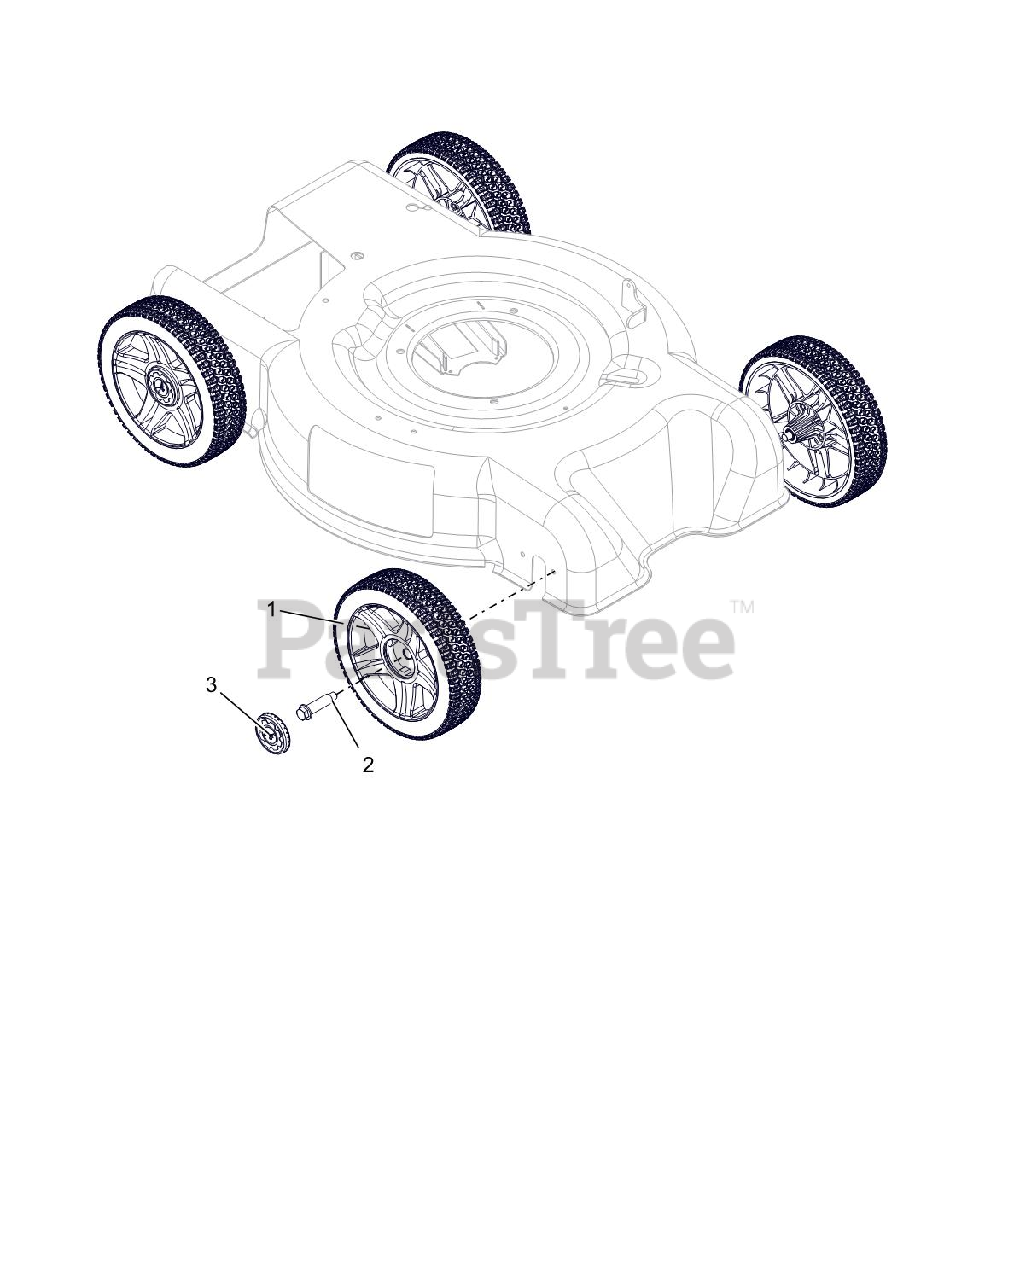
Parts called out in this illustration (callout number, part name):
1	ASSEMBLY, RAZOR WHEEL/BSHG
2	BOLT, WHEEL SHOULDER
3	CAP, LM WHEEL HUB
